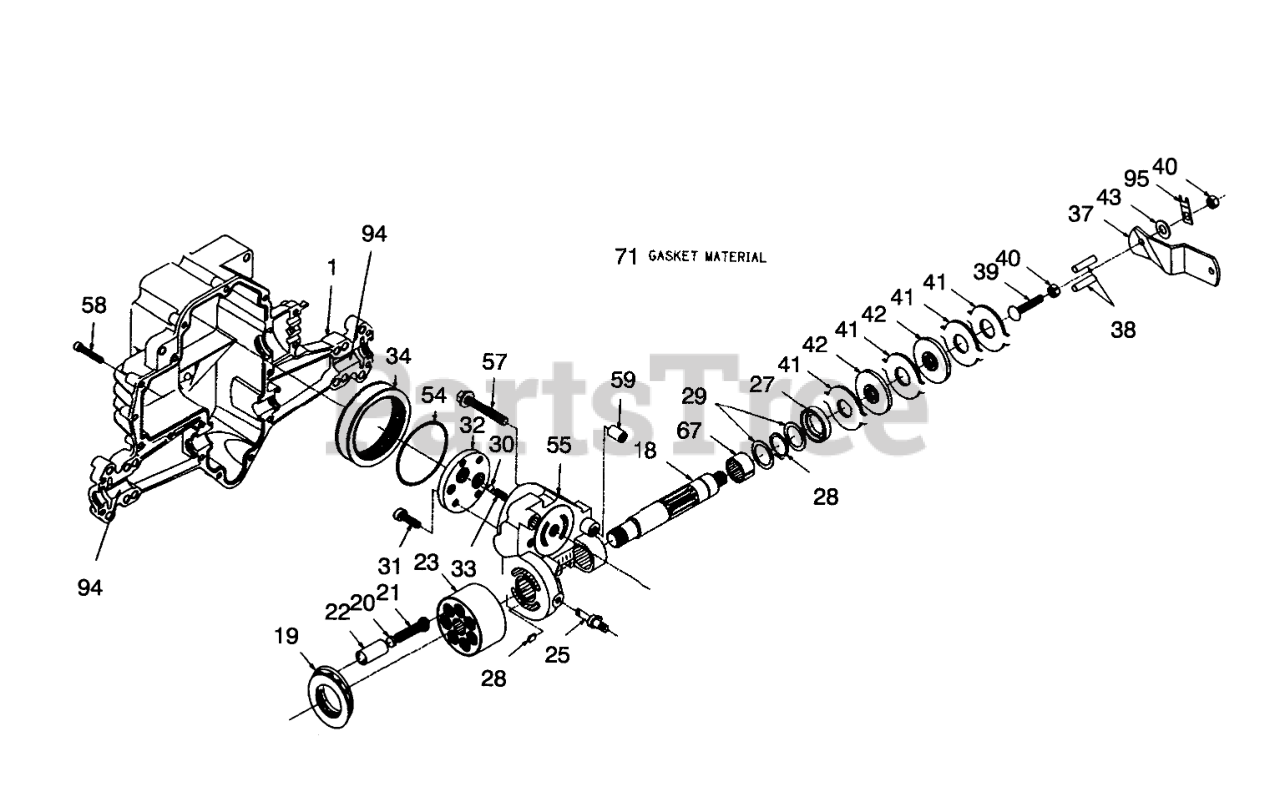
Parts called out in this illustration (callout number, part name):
1	Housing-Lower
18	Shaft-Motor
20	Seat-Piston Spring
21	Spring-Piston
23	Block-Cylinder (Motor)
25	Actuator-Bypass
26	Plate-Bypass
27	Seal-Lip
29	Washer
30	Ball
31	Spring-Check Valve
32	Plate-Check Valve
33	Socket Hd. Cap Screw
34	Oil Filter Element
37	Lever-Brake
38	PIN - ACTUATING
39	Bolt
40	NUT-LOCK, NI
41	Stator-Brake
42	Rotor-Brake
43	WASHER-PIVOT
54	O Ring
55	Center-Section
57	Bolt
58	Bolt
67	Du Bearing
71	Gasket Material
94	Grease Durina "O"
95	STRAP - LOCKING
